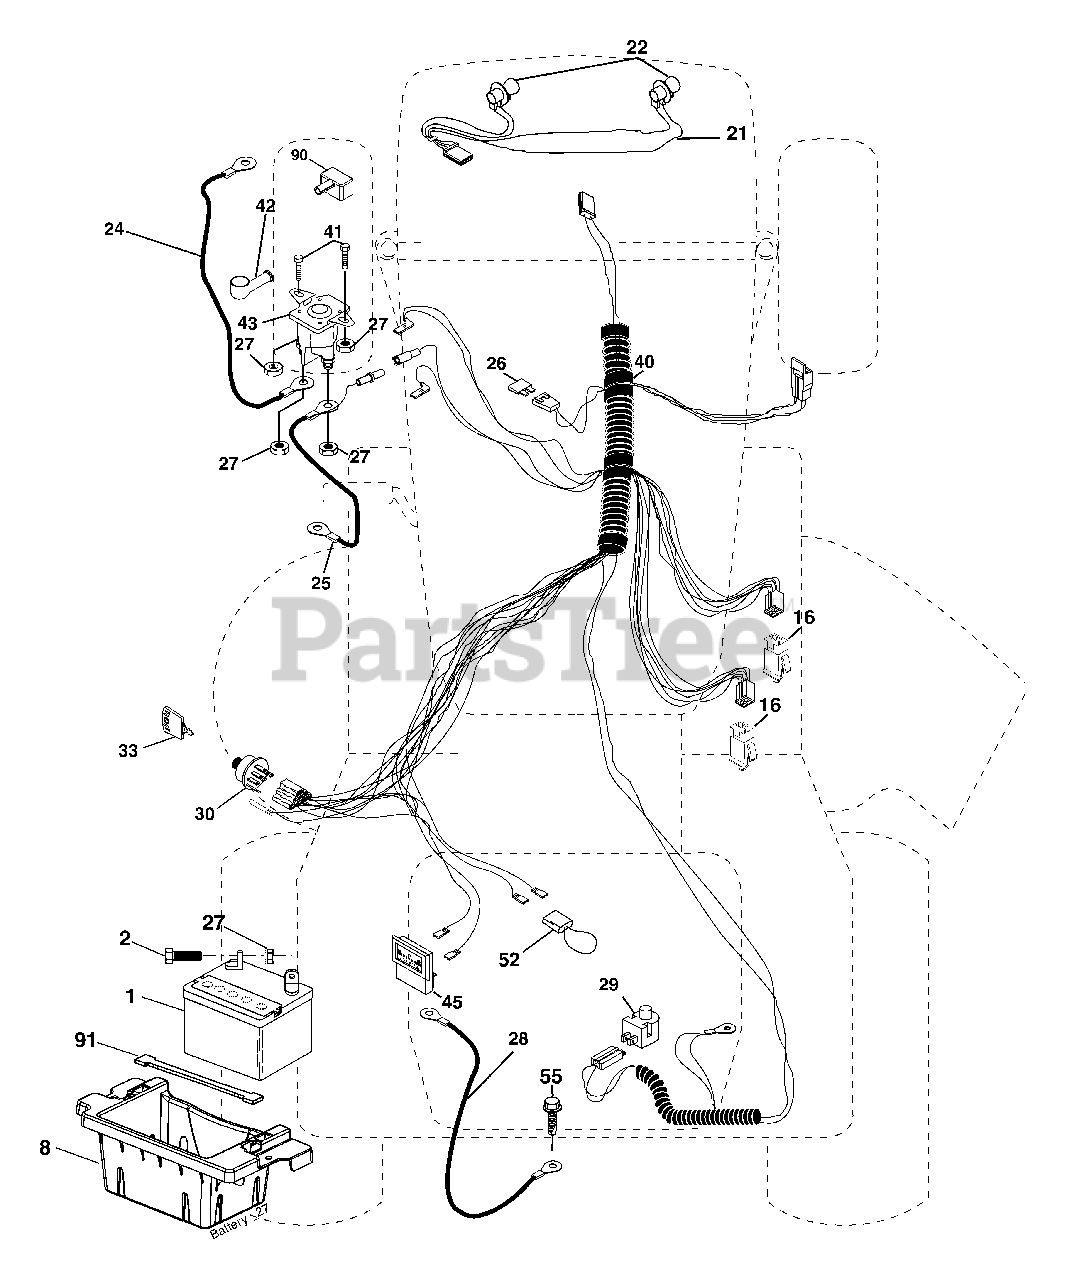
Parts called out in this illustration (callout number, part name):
1	Battery
2	Bolt Hex Hd 1/4-20 unc x 3/4
8	Tray Box
16	Switch Interlock
21	Harness Socket Light
22	Bulb, Light # 1156
24	Cable Battery
25	Cable Battery 6 Ga. Red w/16 wire
26	Fuse
27	Nut Keps Hex 1/4-20 unc
28	Cable Ground 21" Blk 6 Ga.
29	Switch Plunger Nc Gray
30	Switch Ign
33	Key Ign Molded Generic
40	Harness Ign
41	Bolt Fin Hex 1/4-20 unc x 1/2
42	Cover Terminal Red
43	Solenoid
45	Ammeter Rectangular
52	Protection Loop
55	Screw Thdrol 5/16-18 x 1/2
90	Cover terminal Battery
91	Strap Battery
